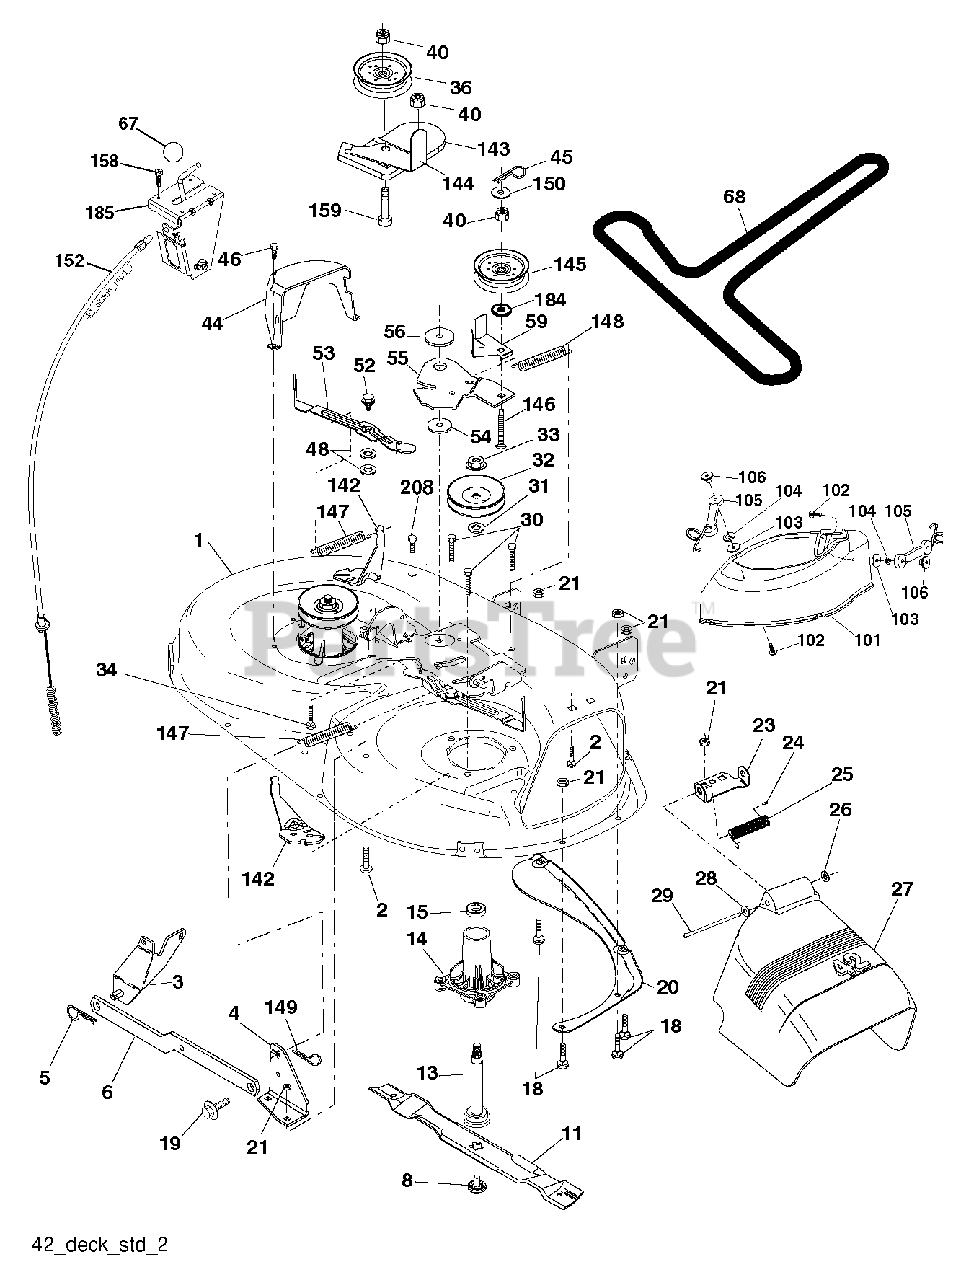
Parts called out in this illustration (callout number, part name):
1	42" DECK KIT
2	BOLT
3	BRKT ASM SWAY BAR
4	BRACKET SWAY BAR 42" DECK
5	RETAINER-SPRNG RB
6	BAR SWAY DECK
8	BOLT.WASHER.ASM.7/16-2
11	BLADE.42".MULCH
13	SHAFT.ASM.MDRL.N/GREASE.38
14	HOUSING MANDREL
18	BOLT
19	BOLT SHD 5/16-18
20	BAFFLE.VORTEX
21	LOCKNUT
23	BRKT.DEFLECTOR.38"2005+
24	CAP-SLEEVE LT
25	SPRING TORSION
27	SHIELD DEFLECTOR
28	WASHER
29	ROD.HINGE
30	SCREW, WASHER HEAD
31	WASHER.SPACER.MANDREL
32	PULLEY/MANDREL
33	NUT.FLANGE.LOCK.TOP
34	BOLT.3/8-16X1.50
36	FLAT IDLER PULLEY
40	NUT LOCK FLG 3/8-16 UNC
44	GUARD MANDREL LH BLACK
45	RETAINER M
46	SCREW.1/4-20X5/8
53	ARM BRAKE ASSY
55	ARM IDLER 42" MOWER LT/YT
56	SPACER.RETAINER.MOWER
67	KNOB T (3/8 HOLE)
106	WELDNUT
142	ANCHOR SPRING BRAKE MOWER
143	BRACKET, ARM IDLER
144	KEEPER.BELT.42".CLUTCH.CABLE
145	PULLEY
146	BOLT, CARRIAGE IDLER BLACK
148	IDLER RETURN SPRING
149	SPRING.RETAINER.YELLOW.ZINC
150	WASHER LT
152	42" CLUTCH CABLE
158	SCREW
159	BOLT
184	WASHER
185	HEAD ASM. CABLE CLUTCH
208	SCREW 3/8-16X1/2
